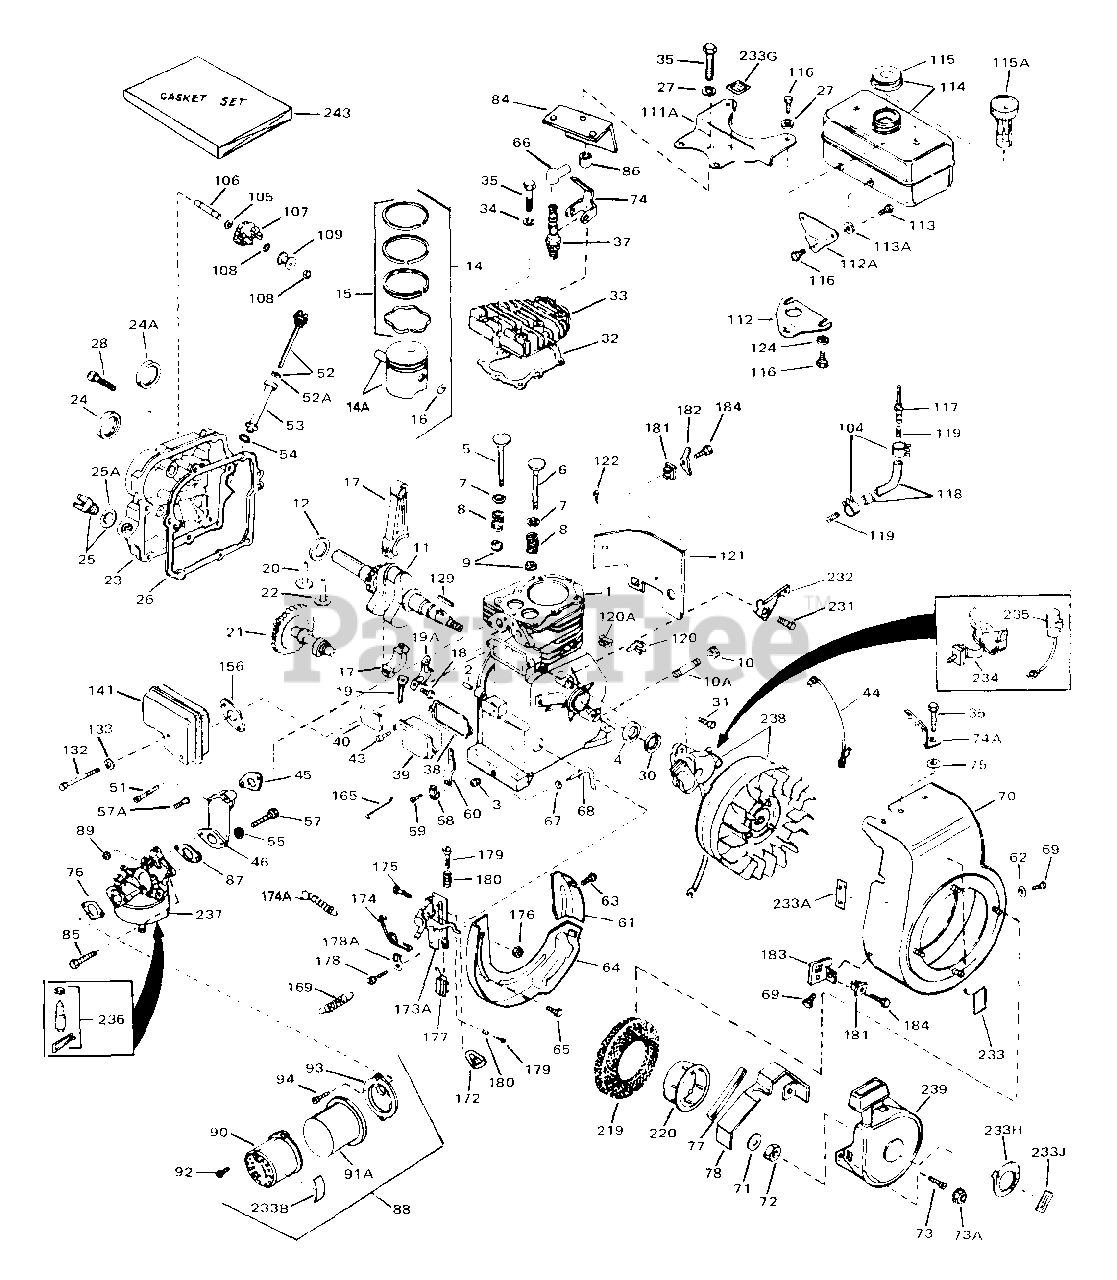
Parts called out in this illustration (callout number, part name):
1	"Cylinder Assy. (2-5/8" Bore)
2	Pin, Dowel
3	Plug, Sq. hd. pipe 1/4-18
4	Seal, Oil
5	Valve, Intake (Standard)
5	Valve, Intake (1/32" oversize)
6	Valve, Exhaust (Standard)
6	Valve, Exhaust (1/32" oversize)
7	Cap, Upper valve spring
8	Spring, Valve
9	Cap, Lower valve spring
11	Crankshaft Assy.
12	Washer, Thrust
14	Piston, Pin & Ring Assy. (Std.) (2-5/ 8 Bore)
14	Piston, Pin & Ring Assy. (.010 oversi ze)
14	Piston, Pin & Ring Assy. (.020 oversi ze)
14A	Piston & Pin Assy. (Standard) (2-5/8" Bore)
14A	Piston & Pin Assy. (.010 oversize)
14A	Piston & Pin Assy. (.020 oversize)
15	Ring Set, Piston (Standard) (2-5/8")
15	Ring Set, Piston (.010 oversize)
15	Ring Set, Piston (.020 oversize)
16	Ring, Piston pin retaining
17	Rod Assy., Connecting
18	Screw, Connecting rod
19	Dipper, Oil
19A	Plate, Lock
20	Lifter, Intake valve
21	Camshaft (Mech. Compression Release)
22	Lifter, Exhaust valve
23	Cover, Cylinder
24	Seal, Oil
25	Plug, Oil filler
25A	Gasket, Oil filler
26	Gasket, Cylinder cover
28	Screw, Hex hd. Sems, 1/4-20 x 1
32	Gasket, Cylinder head
33	Head, Cylinder
34	Washer, Flat
35	Screw, Hex flange hd., 5/16-18 x 1-1/ 2
35	Screw, Hex flange hd., 5/16-18 x 2
35	Screw, Hex hd., 5/16-18 x 2-3/4
37	Plug, Spark (Champion J-8 or equivale nt)
37	Resistor Spark Plug
38	Gasket, Breather
39	Breather Assy.
40	Element, Breather
43	Screw, Fil. hd. Sems, 10-24 x 1/2
44	Wire, Ground (Female fittings both en ds)
45	Gasket, Intake
46	Pipe, Intake
51	Screw, Fil. hd. Sems, 1/4-20 x 1-3/8
57	Screw, Hex hd., 1/4-28 x 1
57A	Screw, Fil. hd., 1/4-28 x 2
59	Screw, Hex washer hd., 8-32 x 5/16
60	Lever, Governor
64	Baffle, Blower housing
65	Screw, Hex washer hd. Durlok, 1/4-20 x 5/8
66	Cover, Spark plug
67	Washer, Flat
68	Rod, Governor
69	Screw, Hex hd. Sems, 1/4-28 x 7/16
70	Housing, Blower (5.56 Dia. starter mt g. bolt
71	Washer, Belleville
72	Nut, Flywheel
73	Screw, Pan hd. Sems, 1/4-28 x 7/16
74A	Clip, Spark plug shorting
75	Lockwasher, 5/16
76	Gasket, Air cleaner
84	Baffle, Heat
87	Gasket, Carburetor
88	Cleaner Assy., Air (Poly)
89	Nut & Lockwasher Assy., 1/4-28
90	Body, Air cleaner
92	Screw, Fil. hd. Sems, 8-32 x 3/8
93	Bracket, Air cleaner
94	Screw, Fil. hd. Sems, 10-32 x 1/2
104	Clamp, Fuel line
105	Washer, Flat
106	Shaft, Mechanical governor
107	Gear Assy., Governor
108	Ring, Retaining
109	Spool, Governor
111A	Bracket, Fuel tank upper
112	Bracket, Fuel tank lower
112A	Bracket, Fuel tank lower
113	Screw, Hex hd. Sems, 1/4-20 x 1/2
113	Screw, Hex hd. Durlok, 1/4-20 x 5/8
113	Screw, Hex hd. w/conical spring washe r,
113	Screw, Hex hd. w/belleville washer, 1 /4-20 x
113A	Washer, Flat (1/4" Plain)
113A	Washer, Flat (1/4")
114	Tank Assy., Fuel (Black Poly) (2 qt.)
115	Cap, Fuel filler (White plastic) (Sta ndard)
115	Cap, Fuel filler (Red plastic)
115	Cap, Fuel filler (Red plastic) (Spurt
116	Screw, Hex washer hd. Sems, self-tap, 1/4-14
118	Line, Fuel (Braided 8.25")
118	Line, Fuel (Braided 16")
118	Line, Fuel (Braided 32")
119	Spring, Fuel line
120	Clip, Fuel line
121	Extension, Blower housing
129	Key, Flywheel
132	Screw, Fil. hd. Sems, 1/4-20 x 2-1/2
132	Screw, Hex washer hd. Durlok, 1/4-20 x 5/8
132	Screw, Hex hd., 1/4-20 x 2-3/8
132	Screw, Hex hd., 1/4-20 x 2-1/4
165	Link, Governor-to-throttle
169	Spring, Extension
173A	Speed Control Assy.
174	Spring, Torsion
175	Screw, Hex washer hd. Sems, self-tap, 10-24
175	Screw, Fil. hd., Sems, 8-32 x 1/2
176	Nut, Lock, 8-32
177	Terminal Assy.
179	Screw, Fil. hd. Sems, 8-32 x 3/4
179	Screw, Hex hd., 10-32 x 1 (Drilled th ru)
180	Spring, Compression
219	Screen, Starter cup
220	Cup, Starter
233A	Decal, Instruction
233B	Decal, Air cleaner
234	Contact Assy., Breaker
235	Condenser
236	Inlet Needle, Seat & Clip Assy.
237	Carburetor
238	Magneto, Tecumseh
239	Starter, Rewind
243	Gasket Set
